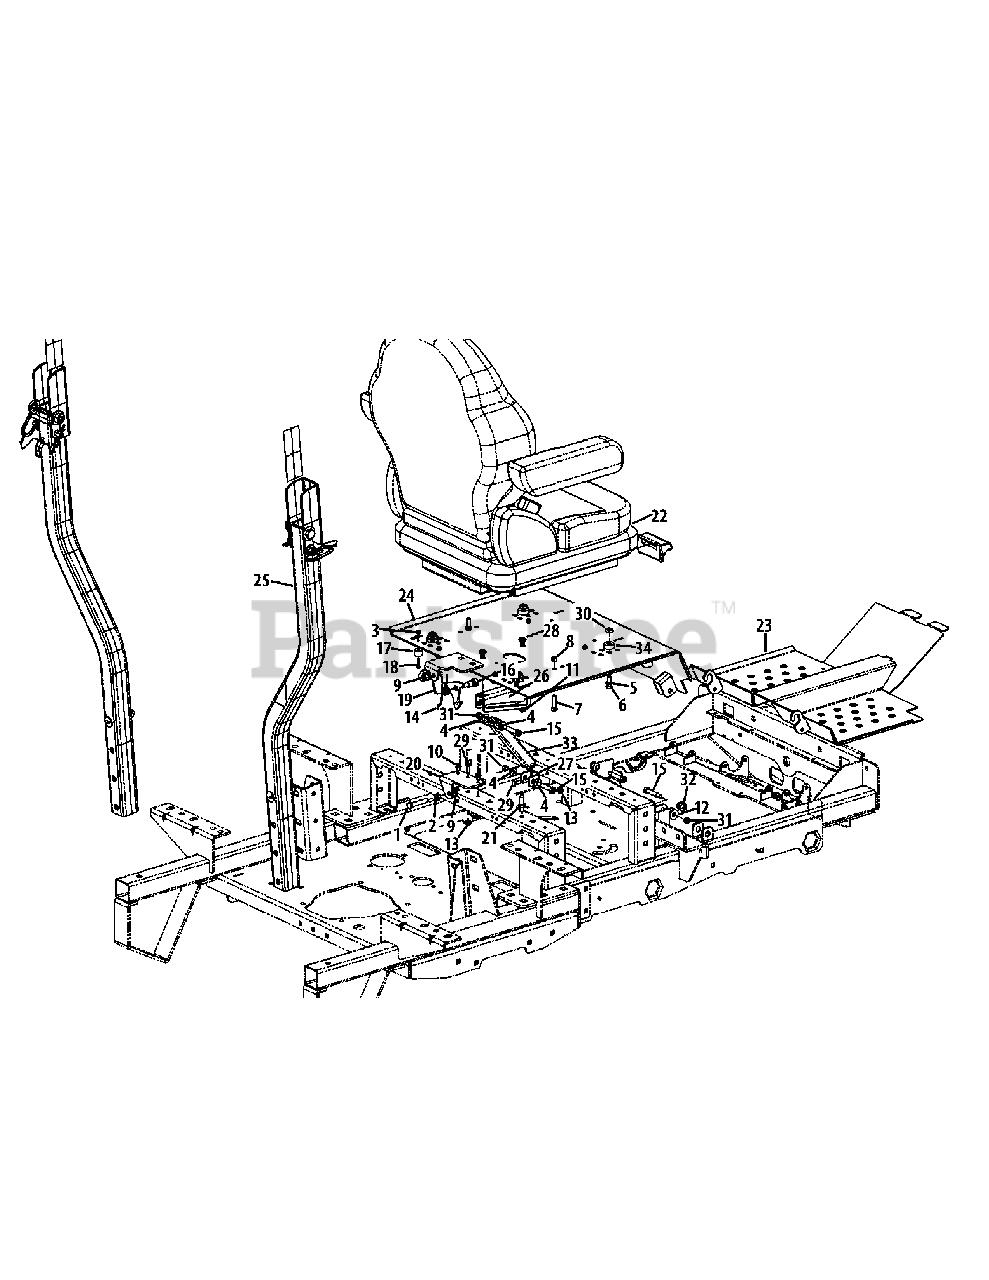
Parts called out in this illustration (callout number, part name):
1	Hex Screw, 3/8-16 x 2.00
2	Nut, 3/8-16
3	Nylock Nut, #10-24
4	Wsdher, .406 x .813 x .063
5	Lock Washer, .312 x .583 x .083
6	Hex Screw, 5/16-18 x 1.00
7	Hex Screw, 5/16-18 x 1.25
8	Flange Lock Nut, 5/16-18
9	Flange Counter Lock Nut, 3/8-16
10	Hex Screw, 1/4-20 x .500
11	Flange Counter Lock Nut, 5/16-18
12	Washer, .406 x 1.00 x .105
13	Flange Top Lock Nut, 1/4-20
14	LH Torsion Spring, .725 x 1.07 x .09
15	Shoulder Bolt, 5/16-18 x .37 x 1.50
16	Shoulder Bolt, 3/8-16 x .50 x .75
17	Bump Stop w/ Washer
18	Flat Head Screw, #10-24 x .750
19	Lever Latch Bracket
20	Mount Latch Bracket
21	Center Adjust Stud, .375 x 1.125
22	Suspension Seat w/ Seat Belt
23	Wide Assembly Floor Panel
24	Seat Mount Bracket Assembly
25	Folding ROPS Assembly
26	Seat Support Lock Bracket
27	Seat Link Pivot Mount Bracket
28	Carriage Bolt, 5/16-18 x .62
29	Hex Screw, 1/4-20 x .75
31	Hex Lock Nut, 5/16-18
32	Grommet, .38 x .75 x .75
34	Spacer, .406 x 1.00 x .38
